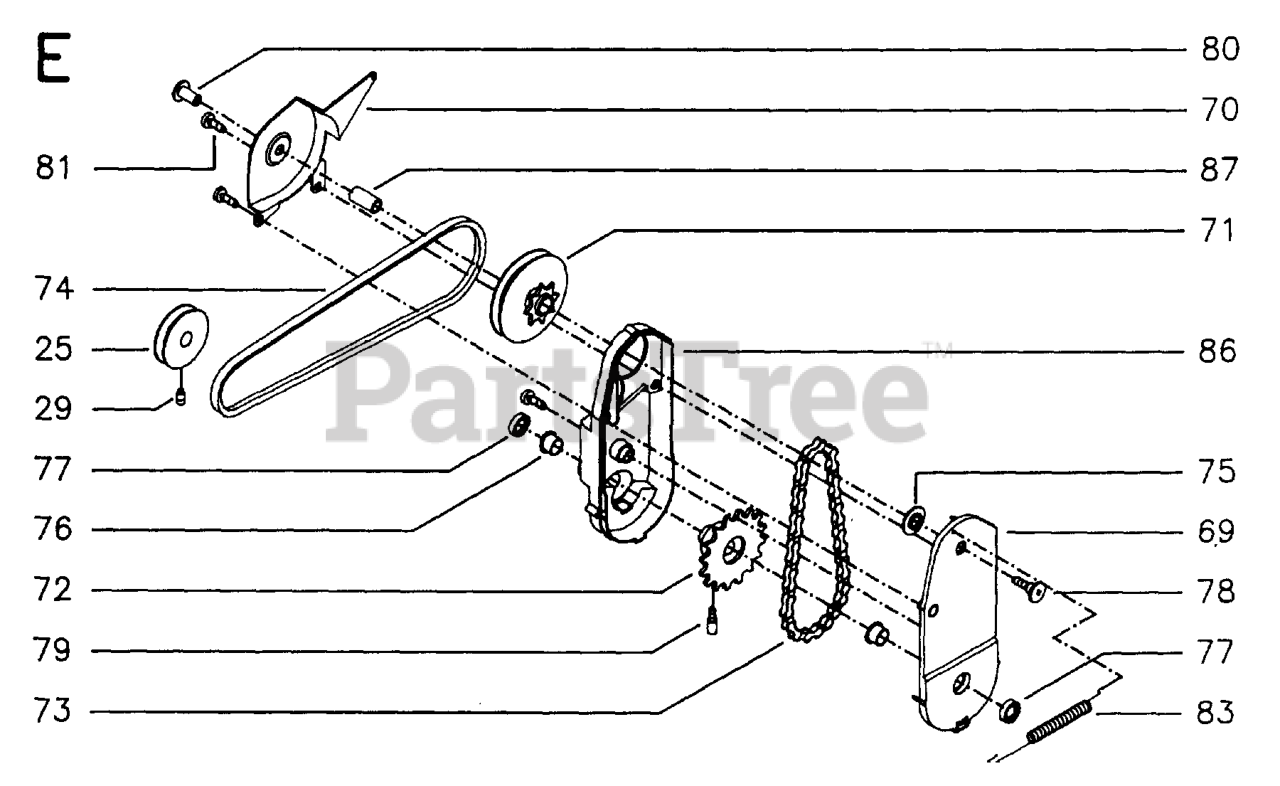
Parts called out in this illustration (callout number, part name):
72	CHAIN WHEEL
74	BELT
76	REPL BY 516 88 29-00
